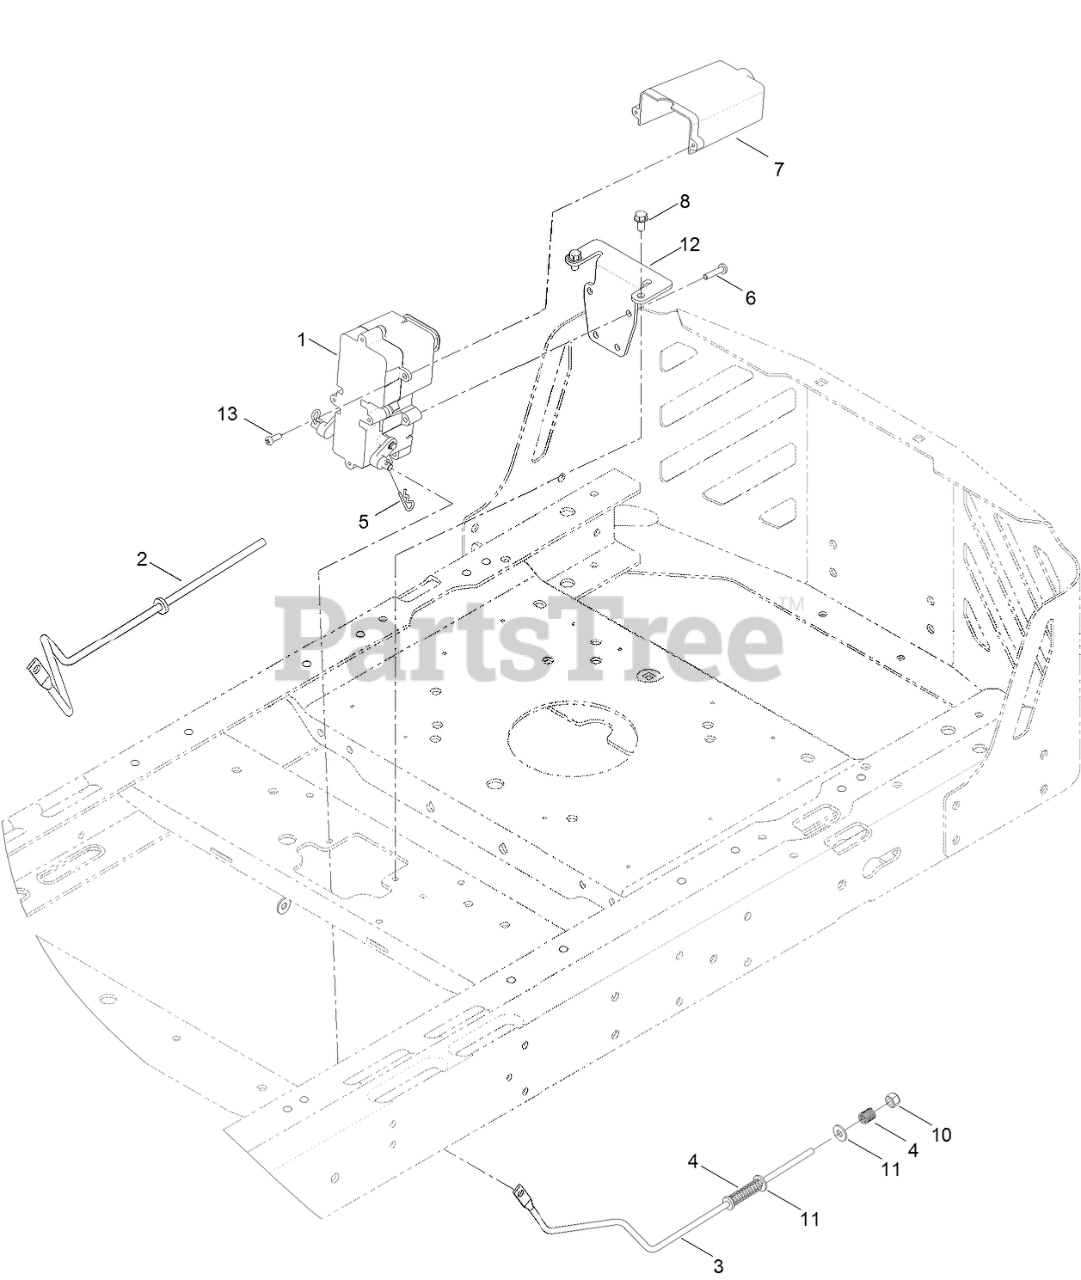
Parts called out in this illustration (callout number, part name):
1	BRAKE BOX ASM
2	ROD-BRAKE, WIDE (RH)
3	ROD-BRAKE, WIDE (LH)
4	SPRING-COMPRESSION
5	PIN-COTTER
6	SCREW-PPH
7	COVER-CONNECTOR
8	SCREW-HWH
10	NUT-LOCK, NI
11	WASHER
12	BRACKET-MOUNT, BRAKE
13	SCREW-PPH
